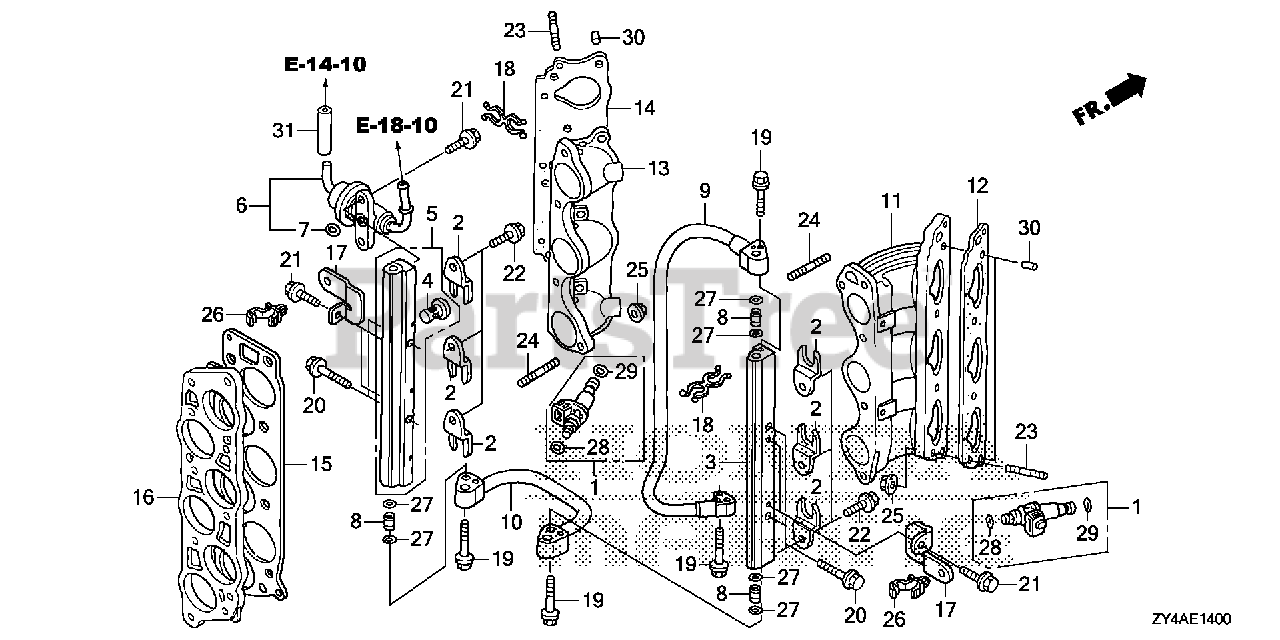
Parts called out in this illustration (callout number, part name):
1	INJECTOR ASSY., FUEL
2	CLIP, INJECTOR
3	PIPE, R. FUEL
4	MESH, FUEL FILTER
5	PIPE, L. FUEL
6	REGULATOR ASSY., PRESSURE
7	O-RING, PRESSURE REGULATOR
8	JOINT, FUEL PIPE
9	HOSE, FUEL
10	HOSE, FUEL JOINT
11	BASE, R. INJECTOR
12	GASKET, FR. INJECTOR BASE
13	BASE, L. INJECTOR
14	GASKET, RR. INJECTOR BASE
15	GASKET, IN. MANIFOLD
16	SPACER, IN. MANIFOLD
17	BRACKET, HARNESS CLIP A
18	CLIP D, SPEEDOMETER CABLE
19	BOLT, FLANGE (6X25)
20	BOLT, FLANGE (6X35)
21	BOLT, FLANGE (6X14)
22	BOLT, FLANGE (6X10)
23	BOLT, STUD (8X28)
24	BOLT, STUD (8X45)
25	NUT, FLANGE (8MM)
26	CLIP, WIRE HARNESS (10MM)
27	O-RING (7.8X1.9) (ARAI)
28	O-RING (7.47X3.6)
29	O-RING (7.45X3.61) (NOK)
30	PIN, DOWEL (10X12)
31	BULK HOSE, FUEL (3.5X3000) (3.5X50)
